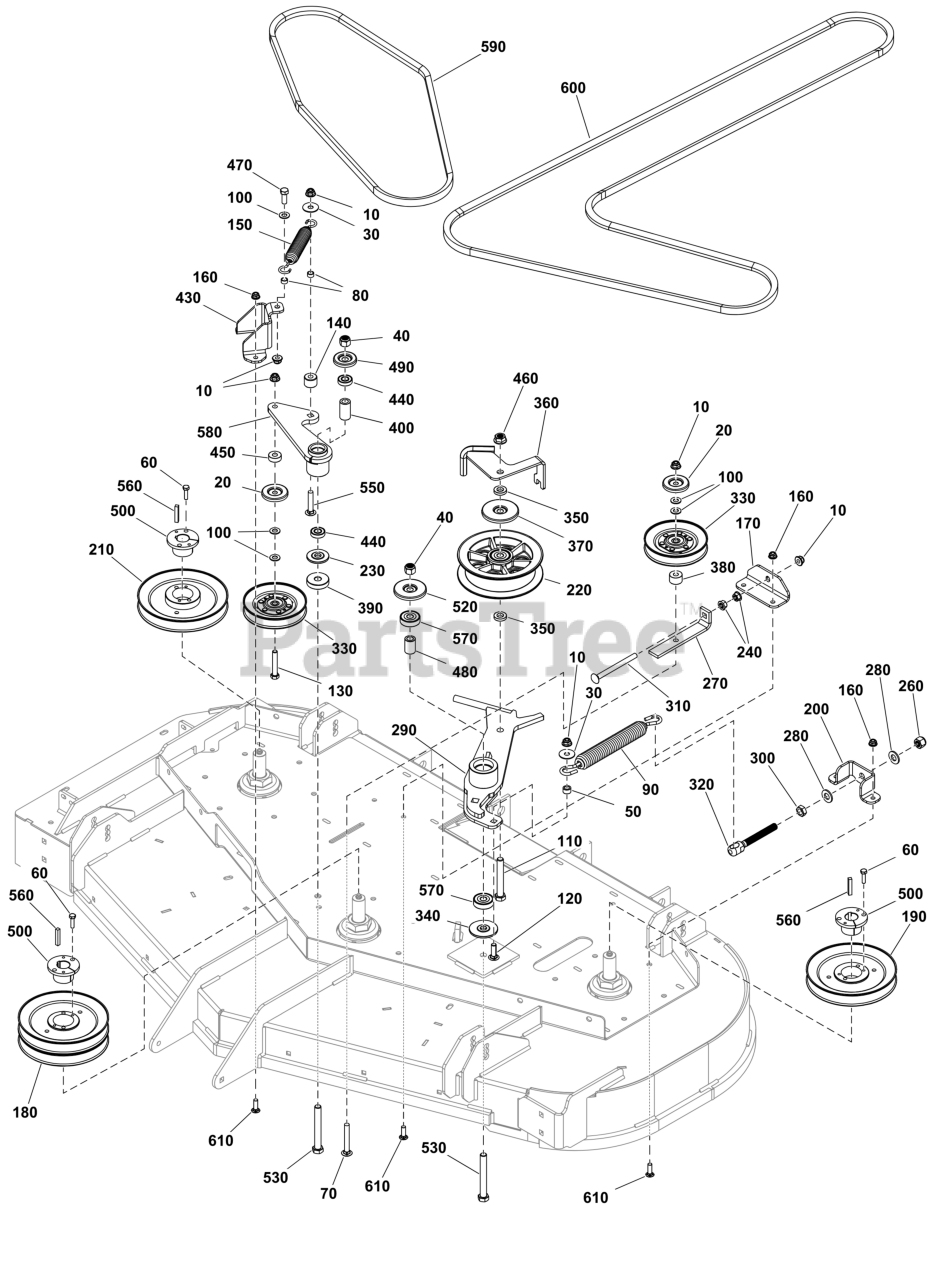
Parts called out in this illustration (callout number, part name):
10	NUT, 3/8-16 HEX NYLOCK
30	WASHER, 3/8" FENDER
60	BOLT, 1/4-20 X 1", GD
70	BOLT, Carriage, 3/8-16 x 2-1/2
80	SPACER, .38 X .50 X .
110	BOLT, 1/2-13 X 3-1/2"
130	BOLT, 3/8-16 X 2-1/4"
150	SPRING, EXTENSION, SW
160	NUT
170	PLATE, PULLER MOUNT, SPRING-BLK
200	PLATE, IDLER BOLT, LONG-BLK
220	PULLEY ASSEMBLY
230	SPACER, IDLER ARM
240	NUT, 3/8-16 HEX SERRA
260	NUT, 1/2-20 HEX NYLON
280	WASHER, 1/2" SAE
290	ARM, IDLER
300	NUT, 1/2-20 HEX JAM
320	ANCHOR, SPRING
350	SPACER .515X1.00X.218
360	GUIDE, BELT
400	SPACER, .52 X .84 X 1
430	PLATE, SPRING MOUNT - BLK
440	BEARING, BALL, AXLE
470	BOLT, 3/8-16 X 1" GD5
480	SPACER, .51 X .84 X 1
490	SHIELD, BEARING, 1/2" ID-1.75"
500	BUSHING, TAPERED HUB
520	SHIELD, BEARING, 1/2" ID-2.5"
530	BOLT, 1/2-13 X 4 GD5
550	BOLT, 3/8-16 X 2", CA
560	KEY 1/4 SQ X 1 1/2
580	WELD, IDLER ARM, RH BELT - BLK
610	BOLT, 5/16-18 X 1", C
